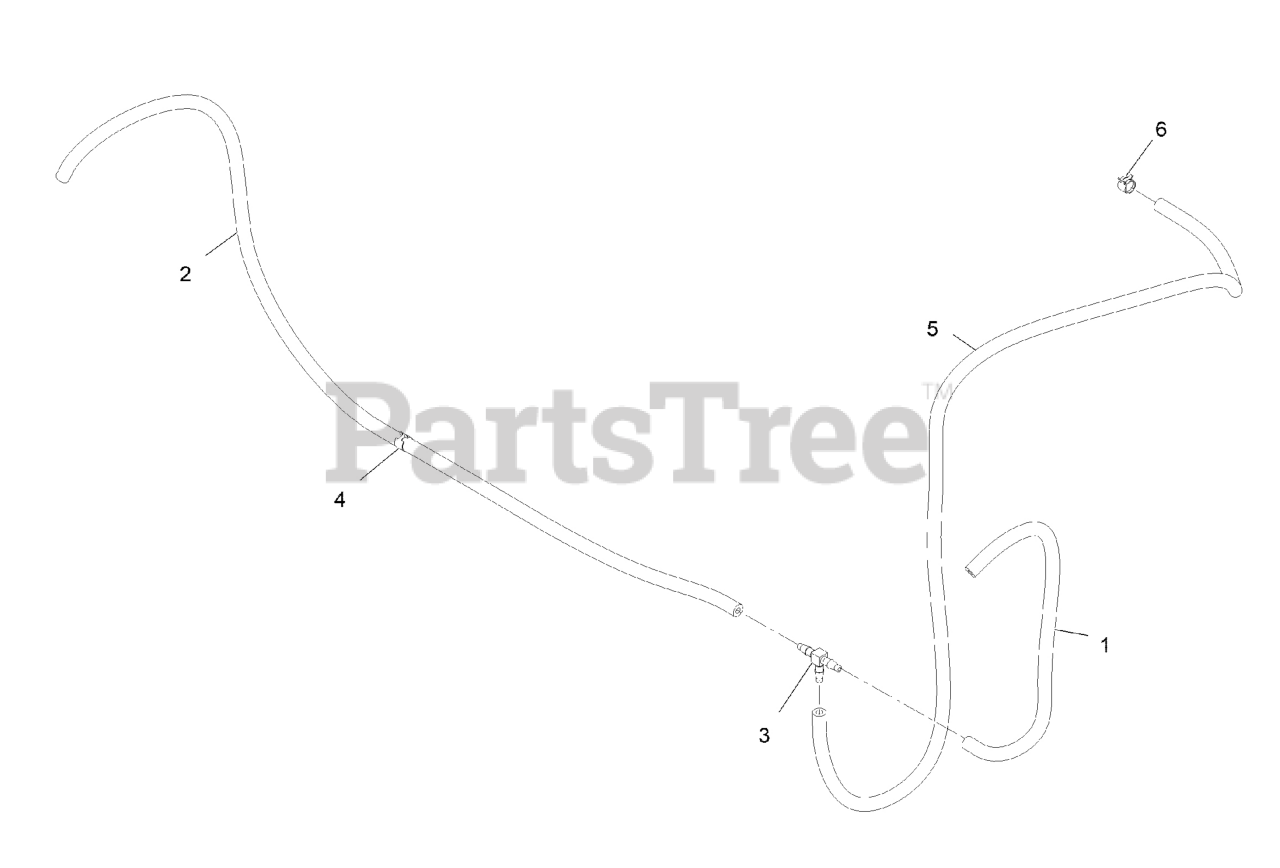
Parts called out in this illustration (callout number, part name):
1	HOSE-FUEL
2	HOSE-LP
3	FITTING-TEE
4	Clamp Hose
5	Hose-Fuel
6	CLAMP-HOSE
